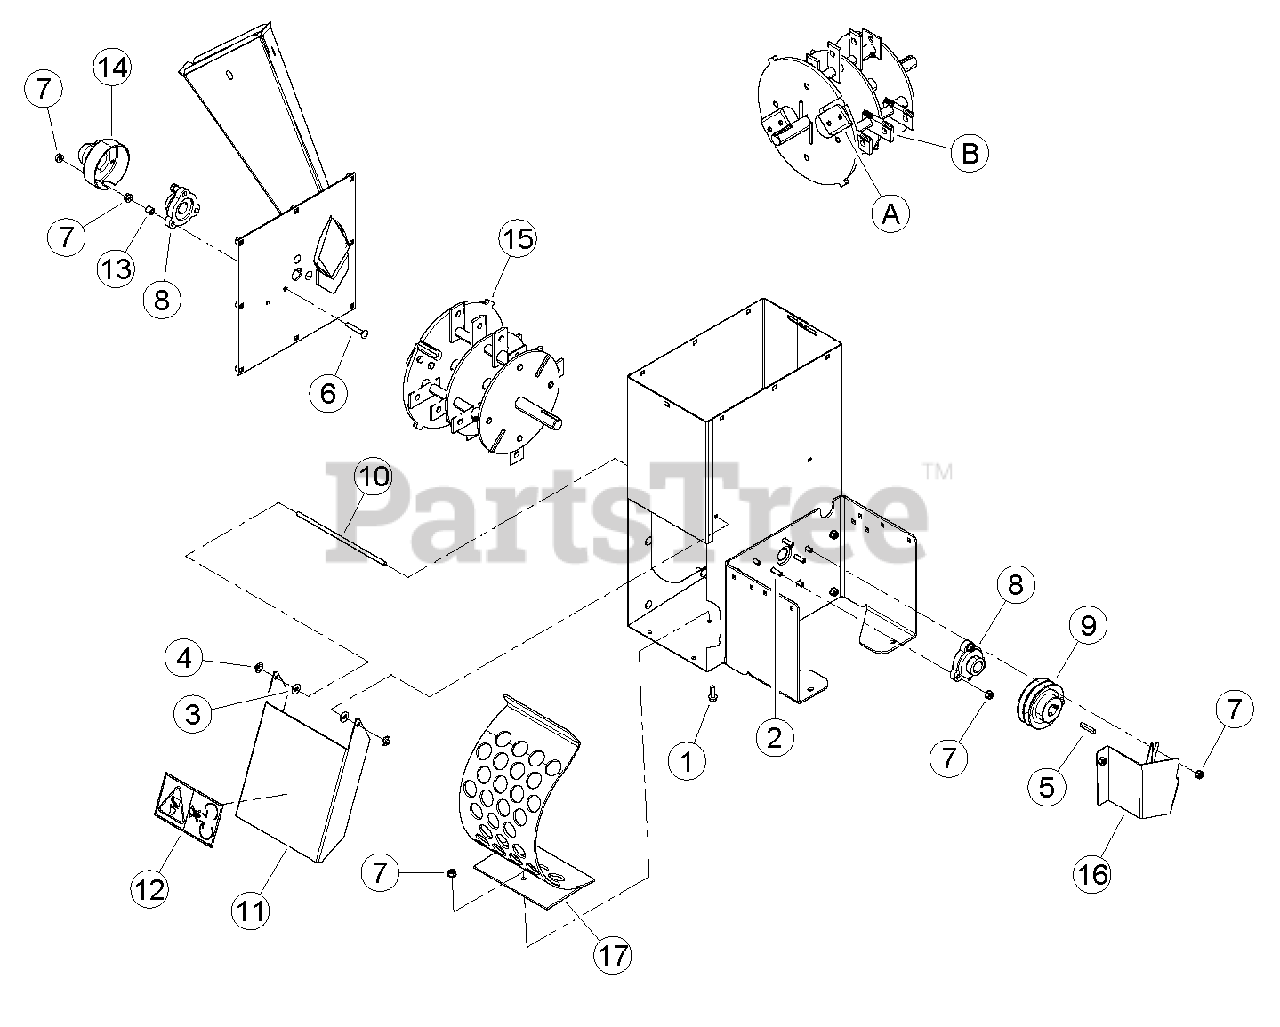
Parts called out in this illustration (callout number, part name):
1	BOLT, 5/16 X 1 FLANGE NC
2	BOLT, 5/16 X 1-1/4 CRG GR5 ZP
3	WASHER, 5/16 ID 7/8 OD NYLON FLAT
4	PUSHNUT, 5/16" ZP
5	KEY, 1/4 SQUARE X 1-1/2 LONG PLAIN
6	BOLT, 5/16 X 2CRG GR5 NC ZP
7	NUT, 5/16-18 NYLOCK-FLANGE
8	BEARING, 1" FLUSHMOUNT CAST W/COLLAR
9	PULLEY, 4X1 2A GROOVE
10	SHAFT, DOOR PIVOT
11	DOOR, 8 HP DISCHARGE W/ DECAL
12	DECAL, BLADE DANGER ISO
13	SPACER, .54 OD X .50 LG
14	CAP, ROTOR SHAFT END CAP
15	ASSEMBLY, ROTOR
16	SHIELD, LOWER
17	WELDMENT, COARSE TAPERED (ALL WIDE BODY MODELS)
A	KIT, CHIPPER BLADES
B	KIT, 3" SHREDDER KNIVES (ALL WIDE BODY MODELS)
